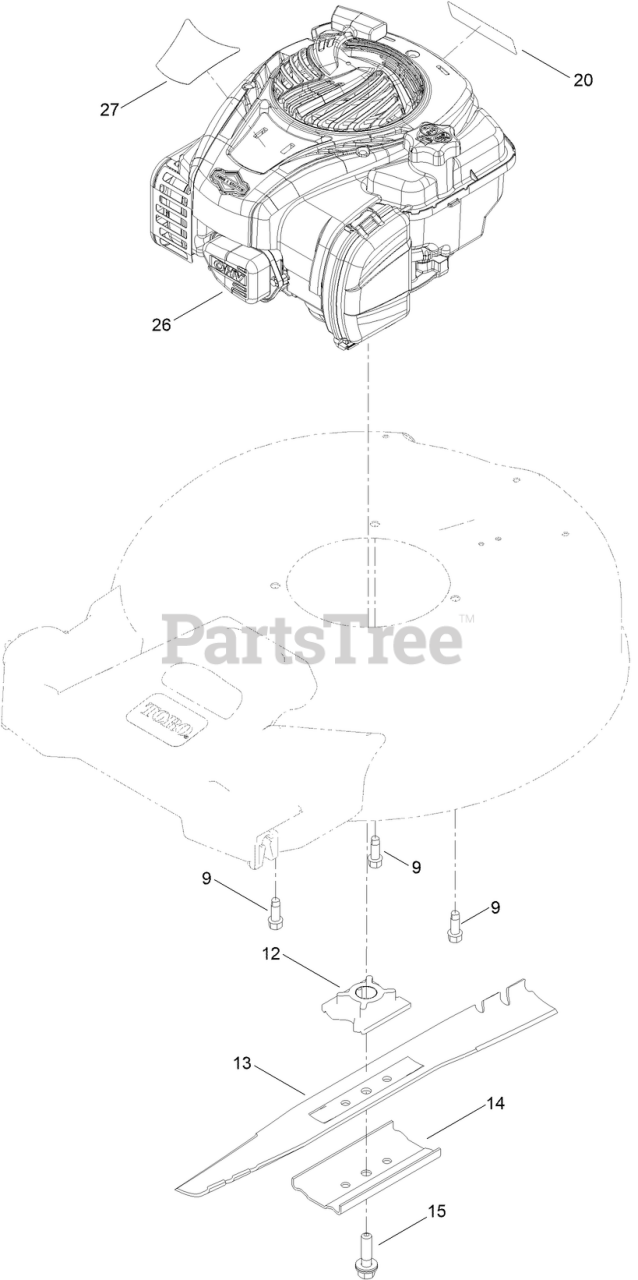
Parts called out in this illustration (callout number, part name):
9	SCREW-TAPTITE
12	RETAINER-BLADE
13	BLADE-21IN
14	SUPPORT-BLADE
15	BOLT-BLADE
20	DECAL-ARRESTOR, SPARK
26	ENGINE-BRIGGS, 550 EX
27	DECAL-ENGINE
